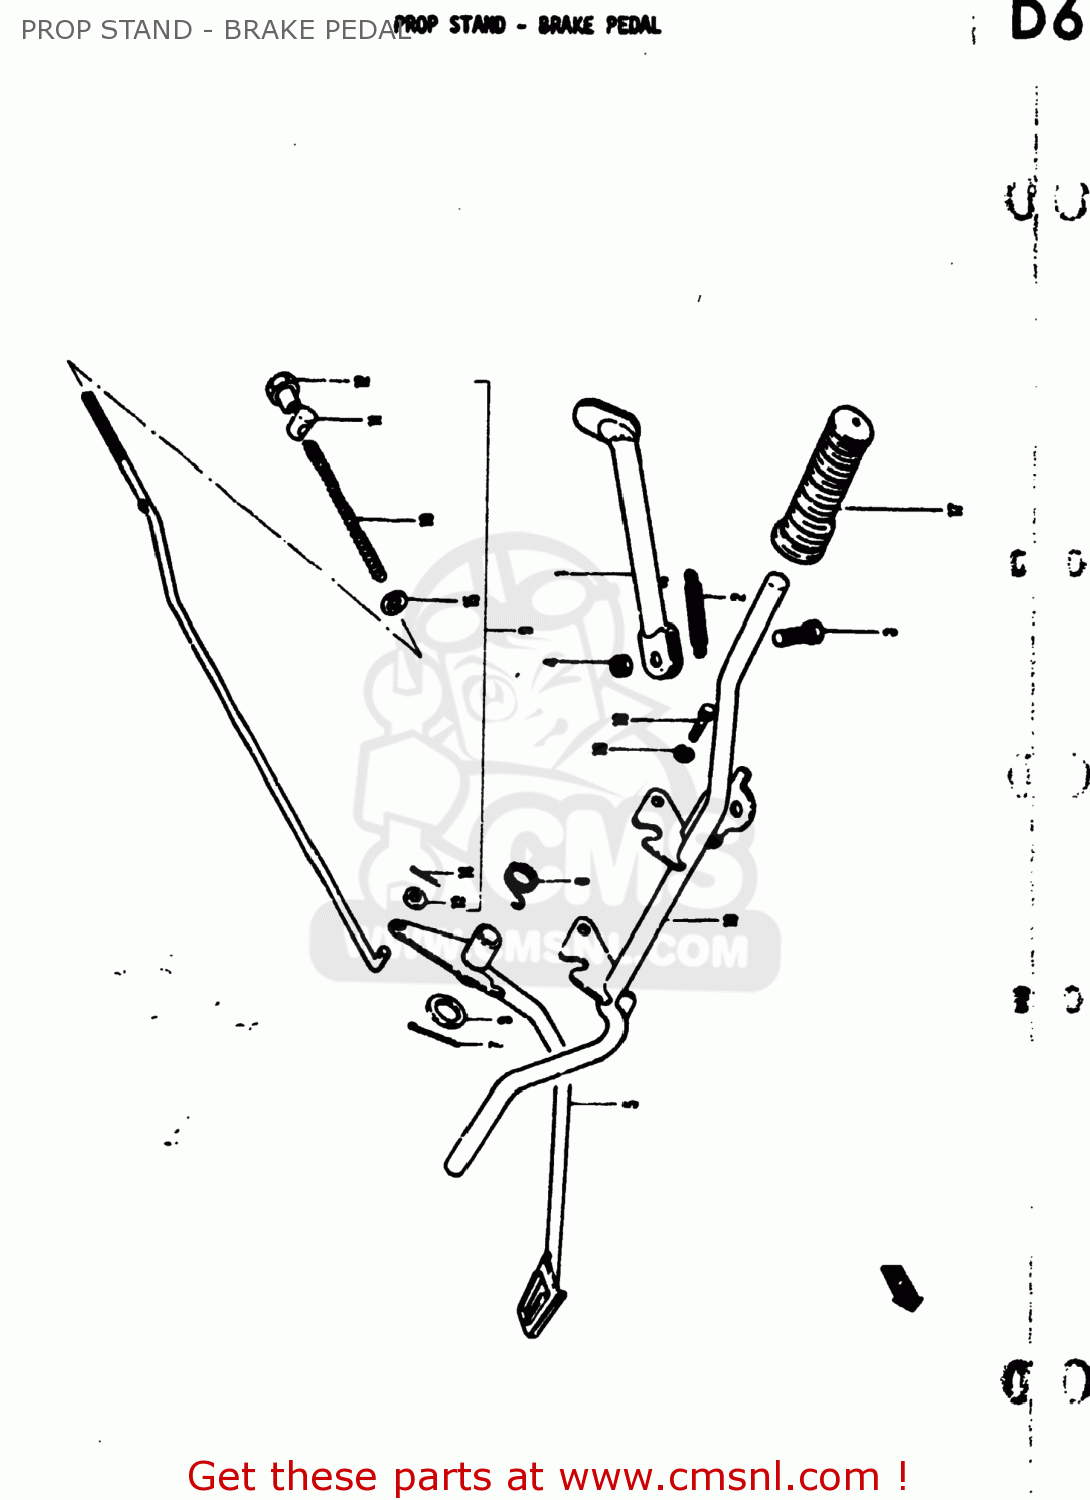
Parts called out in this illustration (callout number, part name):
1	STAND,SIDE
2	SPRING
3	BOLT(10X30)
4	NUT
5	PEDAL,BRAKE
6	SPRING
7	COTTER PIN
8	WASHER(15.5X26X2.3)
9	ROD ASSEMBLY,REAR BRAKE
10	SPRING
11	PIN(11X18)
12	NUT
13	WASHER
14	PIN 20X20
15	WASHER
16	BAR,FRONT FOOTREST
17	RUBBER,FRONT FOOTREST
18	BOLT
19	LOCK WASHER
